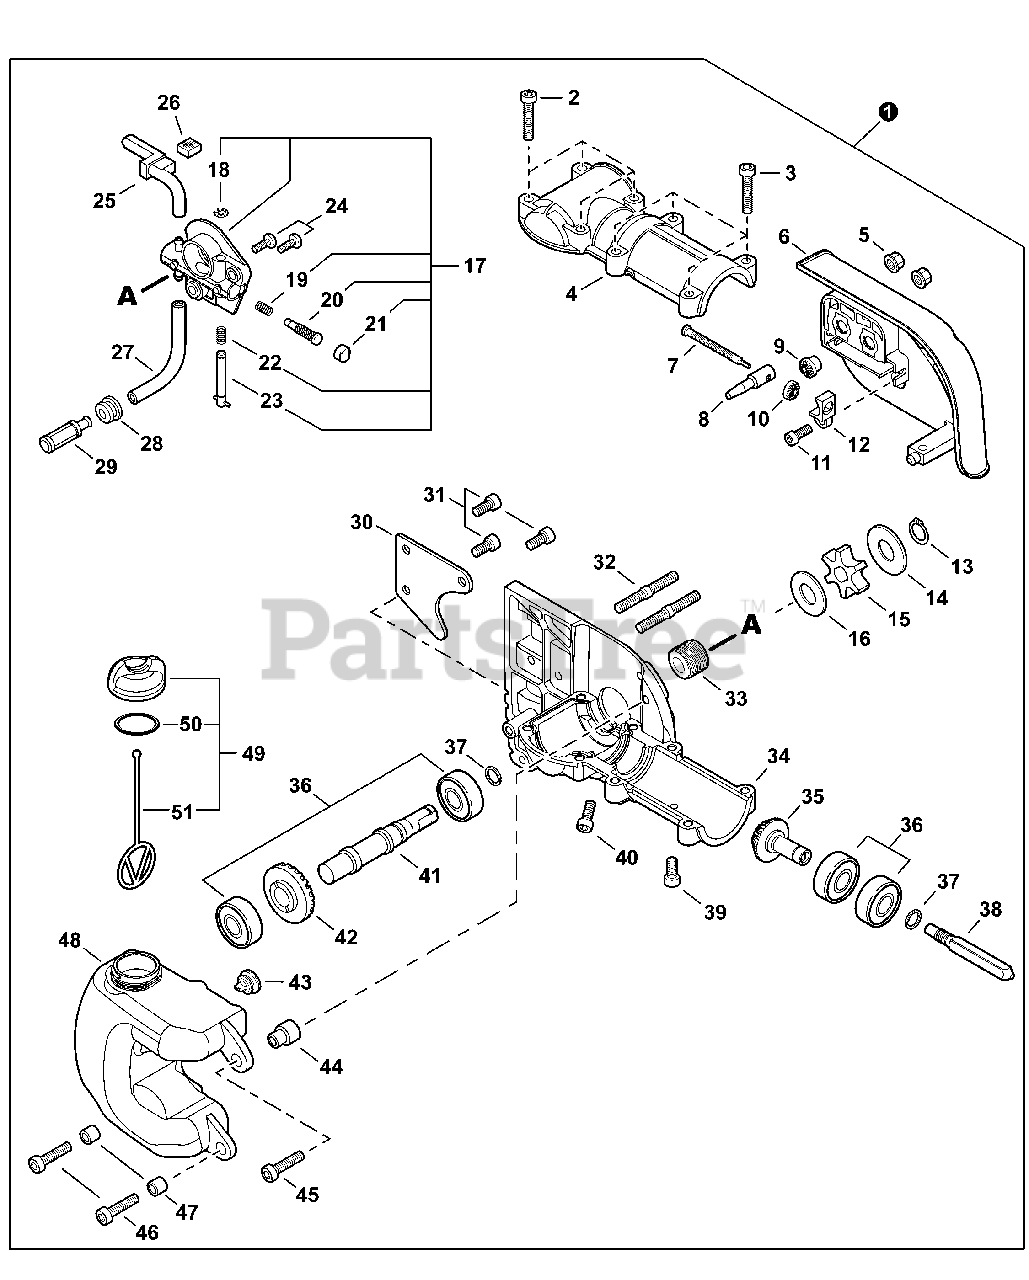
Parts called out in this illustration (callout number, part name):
1	GEAR CASE ASSY
2	SCREW M5×25
3	BOLT 5×25
4	CASE, GEAR - UPPER 35
5	NUT, FLANGE 6
6	GUARD, SPROCKET
8	TENSIONER, CHAIN
9	GEAR - 14 TOOTH
10	GEAR - 14 TOOTH
11	SCREW 4
12	COLLAR 8
13	RING, SNAP
14	WASHER 10
15	SPROCKET, DRIVE
16	WASHER 10.2×24.5×1.2
17	AUTO-OILER ASSY
20	PLUNGER ASSY
21	CAP, OIL PUMP
23	ADJUSTER, OILER
24	SCREW 5×10
25	PIPE, OIL OUTLET
26	PAD, FOAM
27	PIPE, IMPULSE 3×6×70
28	GROMMET
29	FILTER, OIL
31	SCREW 5×10
32	BOLT, STUD 6
33	GEAR, WORM
34	CASE, GEAR
35	GEAR, BEVEL - 15 TOOTH
36	BEARING, BALL
37	RING, SNAP 12
38	CONNECTOR, DRIVE SHAFT
39	BOLT M5×10
40	SCREW 5×10
41	SHAFT, GEAR
42	GEAR, BEVEL - 23 TOOTH
43	VENT ASSY
44	COLLAR 6
45	SCREW M5×25
46	BOLT 5×20
47	SPACER 6.2×7.8×6
48	TANK, OIL
49	CAP ASSY
50	O-RING 18
51	CONNECTOR, CAP L= 60mm
